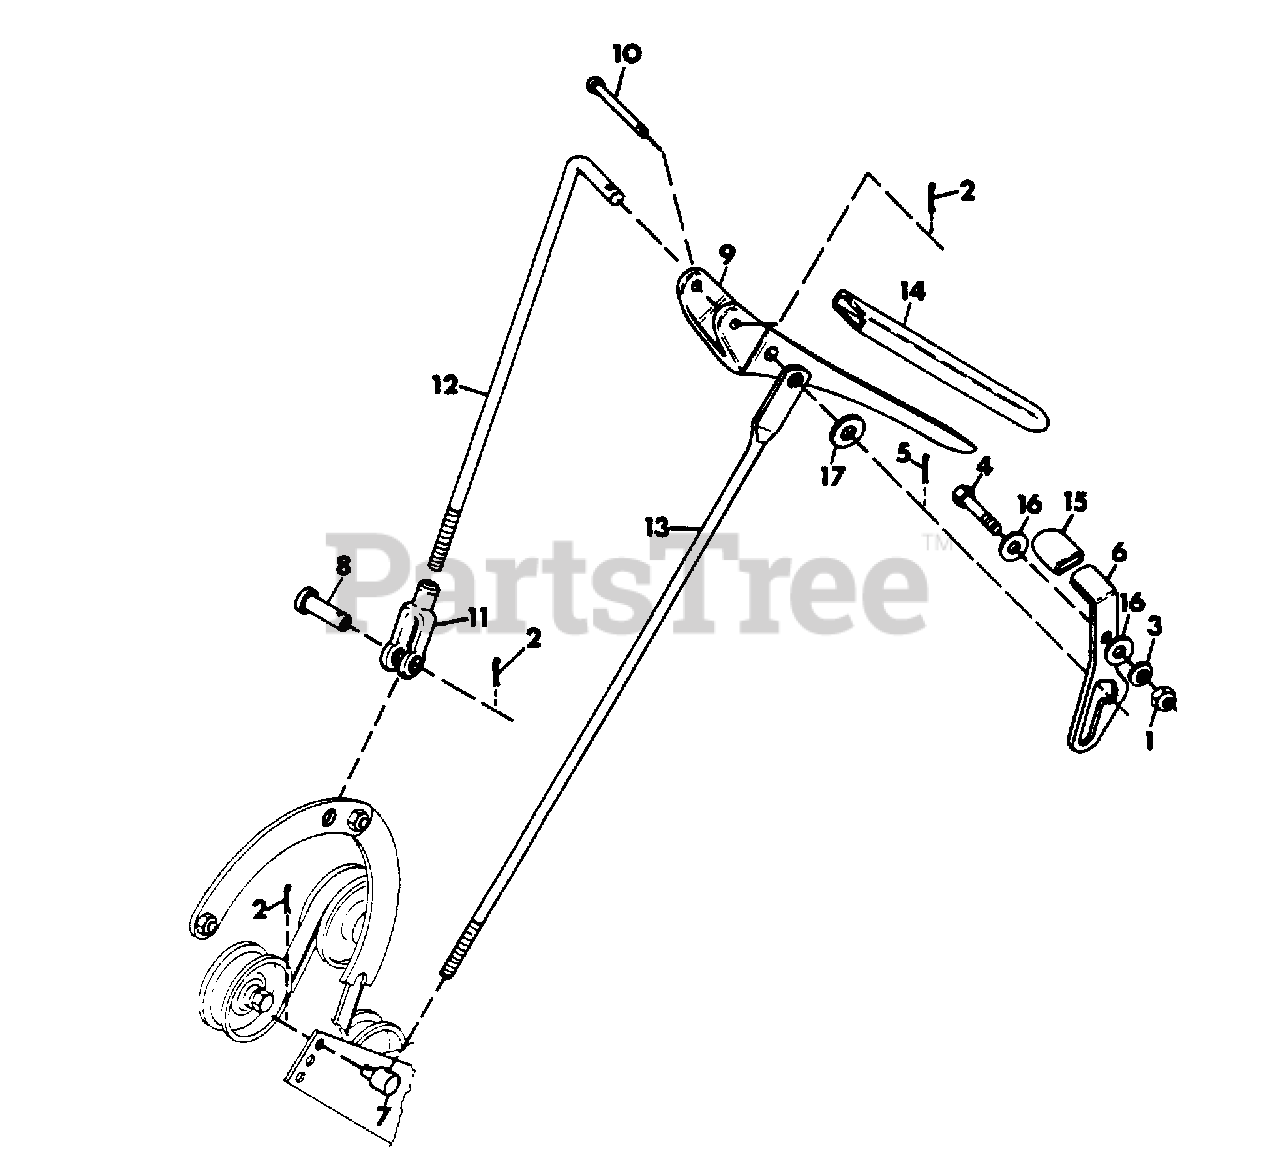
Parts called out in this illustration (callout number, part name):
1	NUT, LOCK 1/4-20
2	PIN, COTTER .09X.75
3	WASHER, SPRING
4	BOLT, HEX 1/4-20X1.75
5	PIN, COTTER .06X.50
6	LEVER, CLUTCH-BRAKE LOCK R.H.
7	PIVOT, BRAKE ROD
8	PIN, CLEVIS .312X.812
9	LEVER, HAND CLUTCH
10	PIN, CLEVIS .187X1.70
11	YOKE
12	ROD, WHEEL CLUTCH
13	ROD, BRAKE
14	GRIP, HANDLE
15	TIP, VINYL
16	WASHER, FRICTION
17	WASHER, FLAT .360X.875X.083
